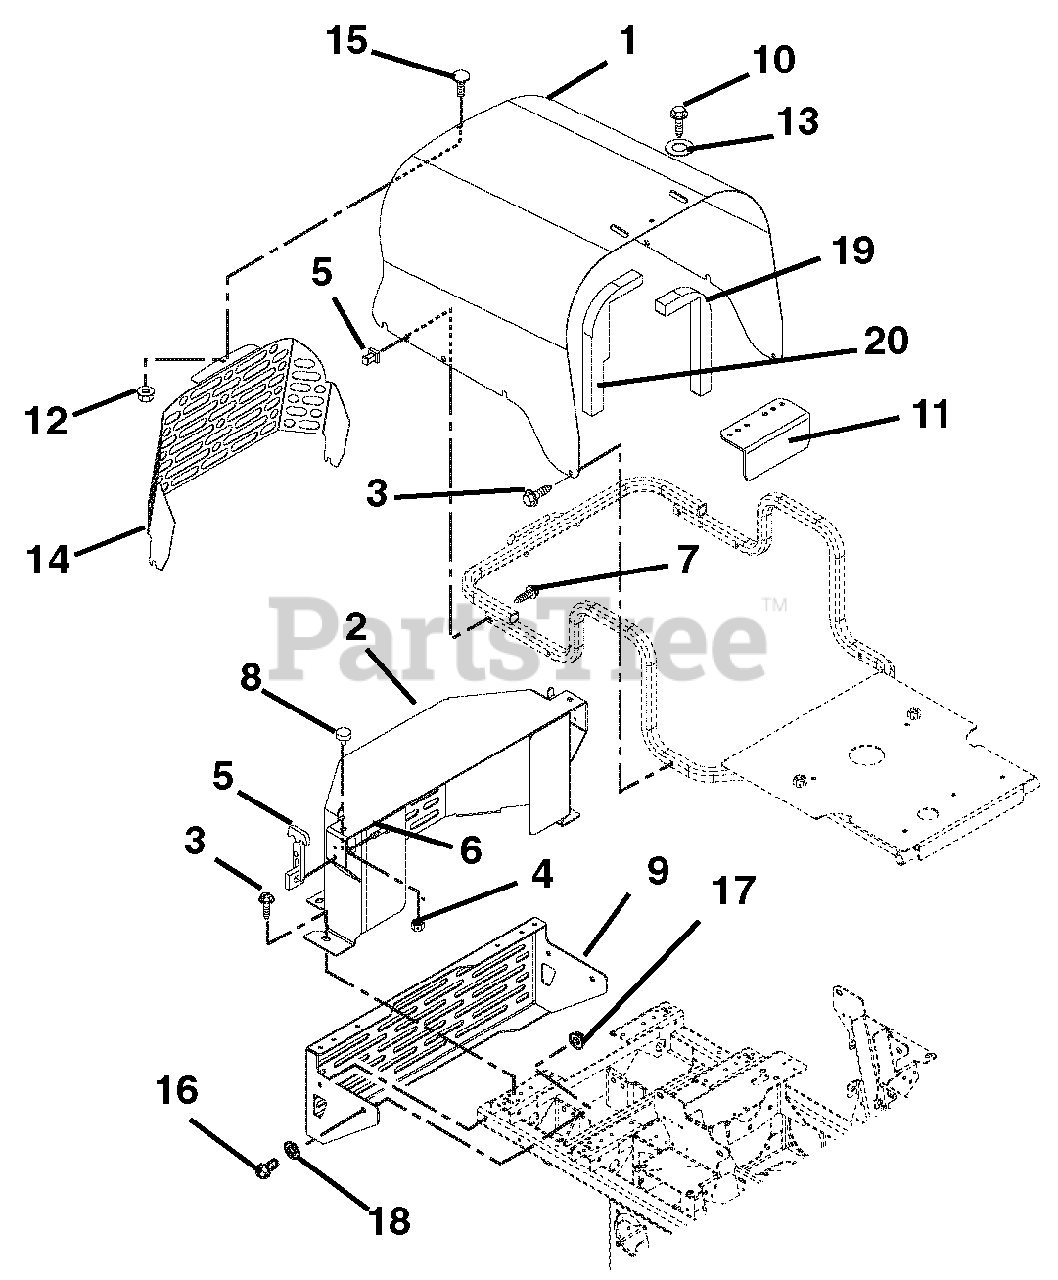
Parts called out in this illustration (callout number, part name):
2	Diesel Belt Guard
3	Screw, Tapping .38-16 x .75 Hex Washer Head
4	Nut, Spin Lock, Flange .312-18
5	Latch, Rubber
6	Screw, Machine 10-24 x .50 Hex Washer Head
7	Screw, Machine 10-24 x 1.50 Hex Washer Head
8	Bumper, Rubber
9	Bumper, Weldment, Rear Diesel
10	Screw, Tapping .25-20 x .50 Hex Washer Head
11	Guard, Radiator Cap
12	Nut, Locking Top Flange .25-20
13	Washer, Flat Steel .281 x .62 x .065
14	Guard, Hood
15	Bolt, Round Head Square Neck .25-20 x .50 Grade 5
16	Bolt, Hex .38-16 x 2.75 Grade 5
17	Nut, Locking Top Flange .38-16
18	Washer, Flat Steel .406 x .812 x.065
19	Dam, Left Side Foam Air
20	Dam, Right Side Foam Air
